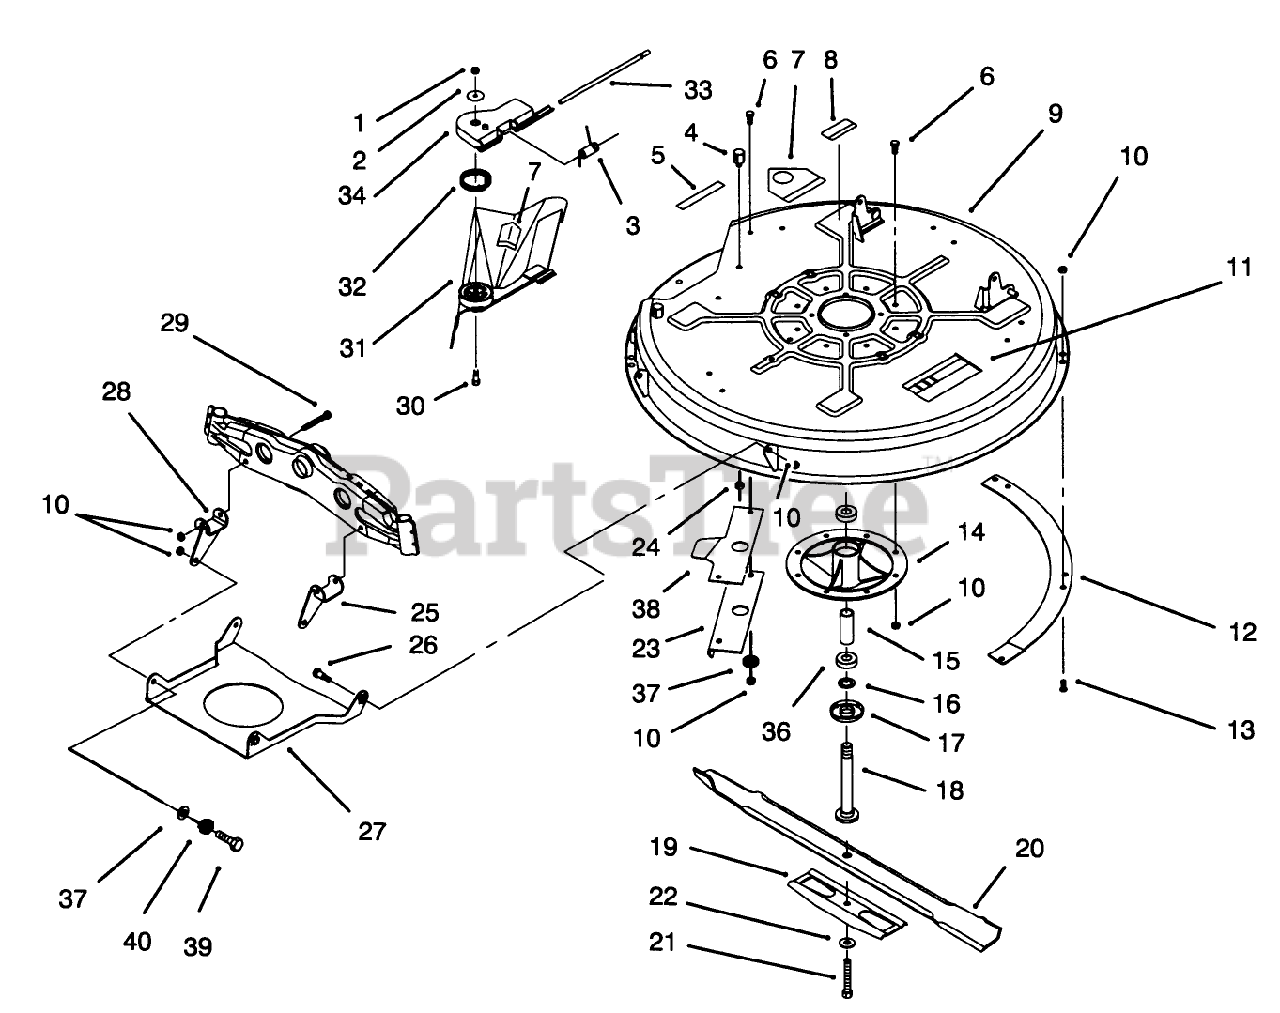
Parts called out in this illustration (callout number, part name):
1	NUT-LOCK, NI
3	SPRING-TORSION
4	POST-PIVOT
5	DECAL-DANGER, DEFLECTOR
6	SCREW-HH
8	DECAL-WARNING
10	NUT-LOCK, NI
11	DECAL-DANGER, THROWN OBJECT
13	SCREW-PPH
14	SPINDLE
15	SPACER-BEARING
16	SPACER-HARDNED
17	SHIELD-BEARING
18	SHAFT-SPINDLE
21	SCREW-HH
22	WASHER-BELLEVILLE
26	BOLT-SHOULDER
29	SCREW-HH
30	BOLT-SHOULDER
32	SPRING-TORSION
33	ROD-HINGE, DEFLECTOR
34	PIVOT-HINGE, DEFLECTOR
36	BEARING-BALL
37	WASHER-PLAIN
39	SCREW-HH
